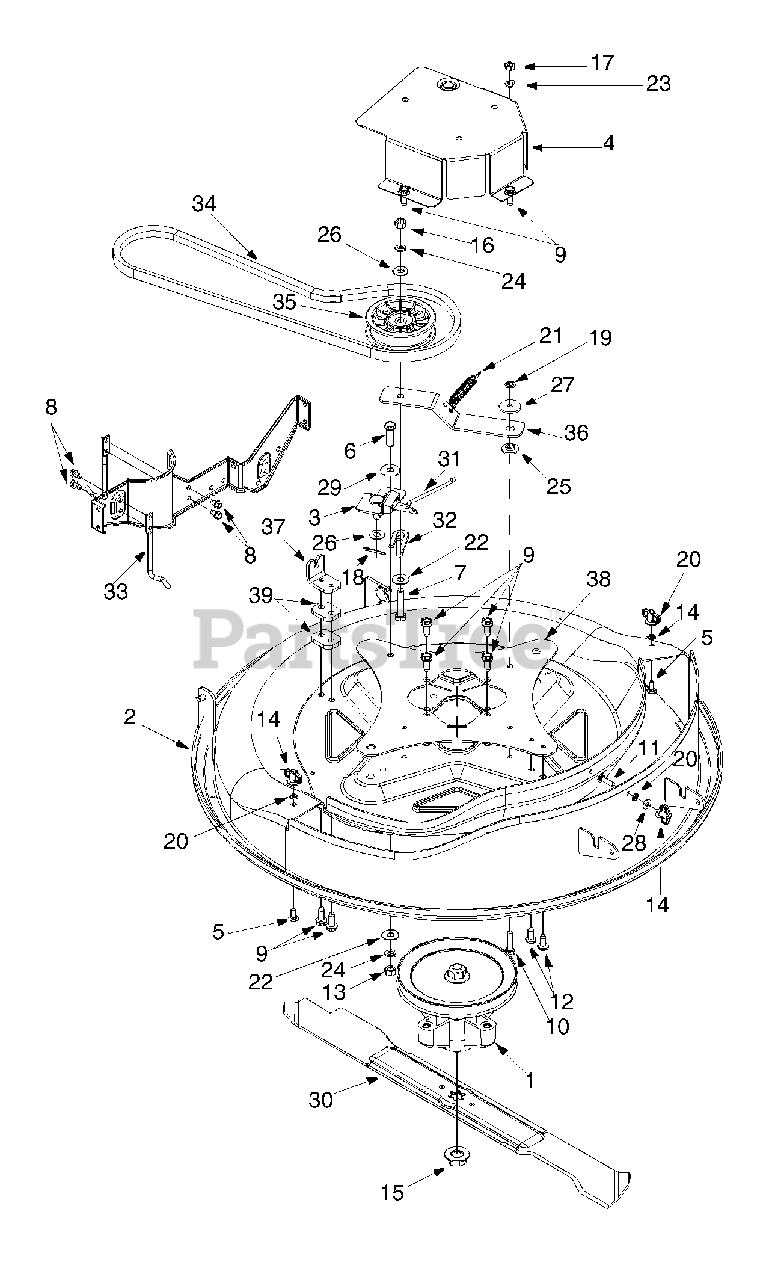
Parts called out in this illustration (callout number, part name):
1	Spindle Assembly
5	Carriage Screw 1/4-20 x .62
6	Hex Bolt 3/8-24 x 1.25 Grade 8
7	Hex Screw 3/8-16 x 1.75 Gr. 5
8	Self-Tapp. Screw 1/4-20 x .5
9	Self-Tapp. Screw 5/16-18 x .75
10	Hex Cap Scr. 5/16-24 x 1.25
11	Carriage Screw
12	Torx Screw 5/16-18 x .75
13	Hex Nut 3/8-24
14	Wing Nut With Bell Washer
15	Flange Nut 5/8-18
16	Hex Nut 3/8-16
17	Hex Nut 5/16-24
18	Cotter Pin
19	Speed Nut
20	Push Nut
21	Extension Spring
22	Flat Washer 3/8 x 1.00 x .030
23	Lock Washer 5/16
24	Lock Washer 3/8
25	Bushing
26	Flat Washer .406 x .875 x .059
27	Flat Washer .330 x 1.25 x .120
28	Flat Washer
29	Spacer
32	Belt Keeper
35	Flat Idler Pulley
